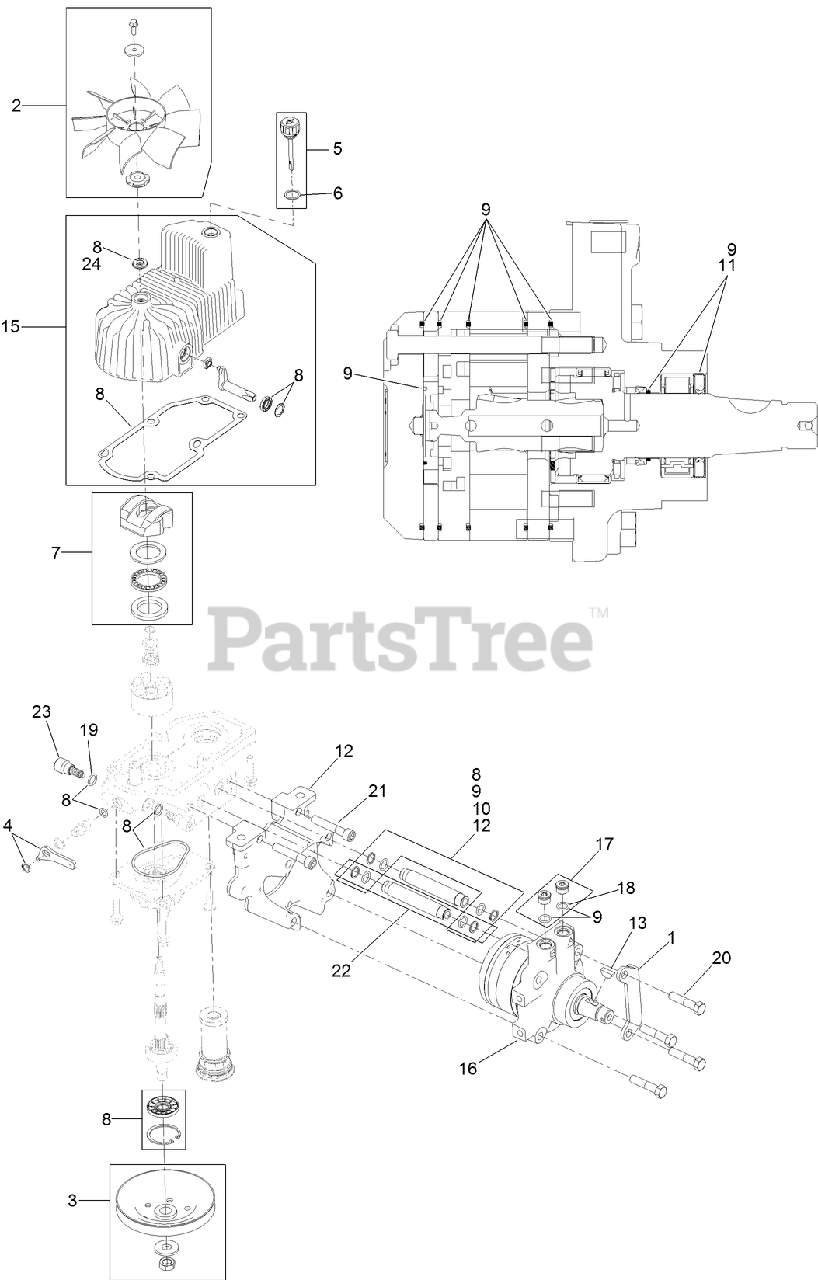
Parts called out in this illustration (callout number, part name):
1	MOUNT-SHOE, HORSE
2	FAN KIT
3	PULLEY KIT
4	HANDLE-BYPASS VALVE, HYDRO
5	DIPSTICK-HYDRO W/GASKET
6	GASKET-DIPSTICK, HYDRO
7	SWASH BLOCK KIT
8	PUMP SEAL KIT
9	MOTOR SEAL KIT
10	TUBE SEAL KIT
11	OUTPUT SHAFT SEAL KIT
12	NOSE CUP-UHT
13	KEY-WOODRUFF
15	HOUSING-HYDRO, RH
16	MOTOR-HYDRAULIC, RH 280CC
17	MAGNETIC PLUGS SERVICE KIT
18	O-RING
19	O-RING-CHECK VALVE
20	SCREW HH
21	SCREW-HSH
22	HYDRAULIC TUBE KIT
23	SHOCK VALVE, 16CC HYDRO
24	SEAL-FAN DRIVE
99	PULLER-PULLEY
